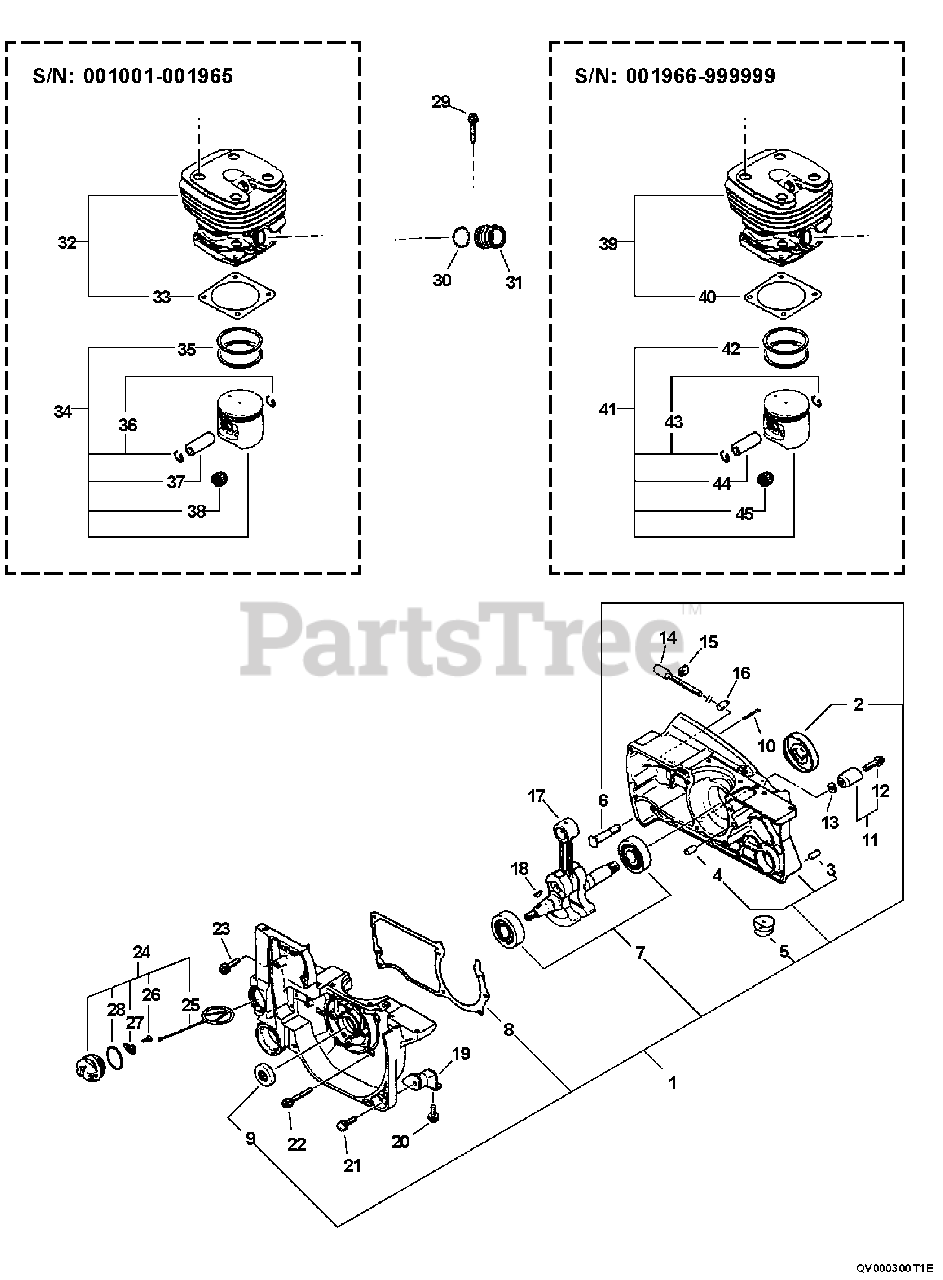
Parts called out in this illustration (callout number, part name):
1	CRANKCASE KIT - GRAY
2	SEAL, OIL
3	PIN - SPRING -- 5X10
4	PIN - LOCATING
6	STUD, GUIDE BAR
7	BEARING, BALL - 6203
8	GASKET, CRANKCASE
9	SEAL, OIL
10	VENT, TANK
11	CHAIN CATCHER KIT
12	SCREW - 5X20
13	WASHER - 5
14	SCREW, TENSIONER
16	TENSIONER, CHAIN
17	CRANKSHAFT ASSY
20	SCREW - 5X14
21	SCREW - 5X14
22	SCREW - 5X35
23	SCREW - 5X20
24	CAP ASSY
25	CONNECTOR, CAP
26	SCREW - 3X8
27	RETAINER
28	O-RING - 25
29	SCREW - 6X25
31	ADAPTOR, INTAKE
32	CYLINDER KIT
33	GASKET, CYLINDER
34	PISTON KIT
35	RING, PISTON
36	RING, RETAINING
37	PIN, PISTON
38	BEARING, NEEDLE
39	CYLINDER ASSY
40	GASKET, CYLINDER
41	PISTON KIT
42	RING, PISTON
43	RING, RETAINING
44	PIN, PISTON
45	BEARING, NEEDLE
